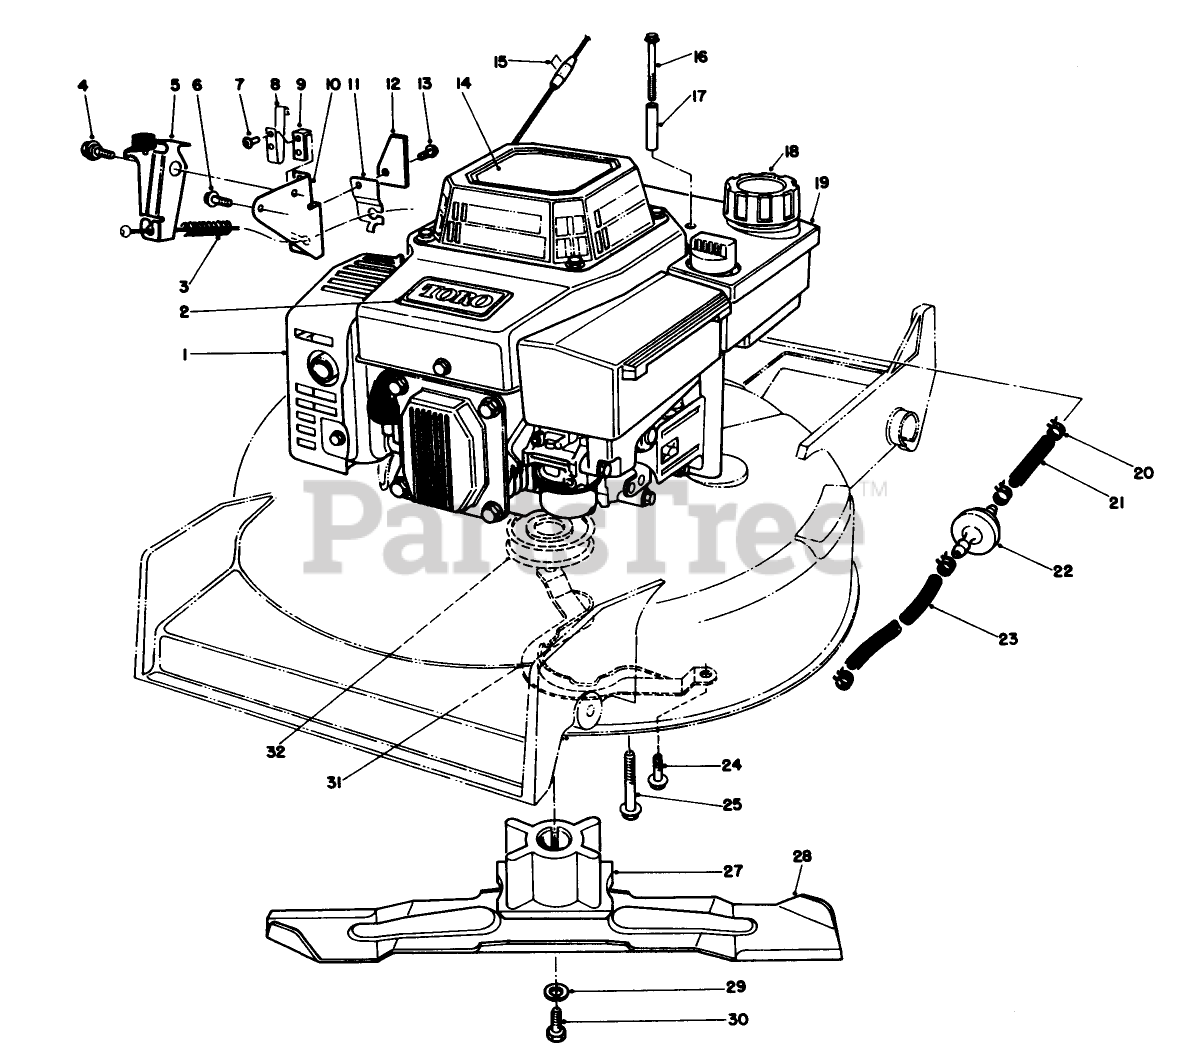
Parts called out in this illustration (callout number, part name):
3	SPRING-COMPRESSION
5	BRAKE PLATE ASM
7	RIVET-PLASTIC
8	STRAP-GROUND
11	CABLE CLAMP
12	STOP-GROUND STRAP
13	SCREW
14	Decal-Recoil
15	Staple
16	THRD FORMING SCREW
17	TUBULAR SPACER
18	GAS CAP ASM
19	TANK ASM
20	CLAMP-FUEL LINE
21	HOSE-FUEL
22	FILTER-FUEL
23	HOSE-FUEL
24	SCREW-HWHTF
27	BLADE RETAINER
29	WASHER-LOCK
30	SCREW-BLADE
32	PULLEY-DRIVE, ZONE START
